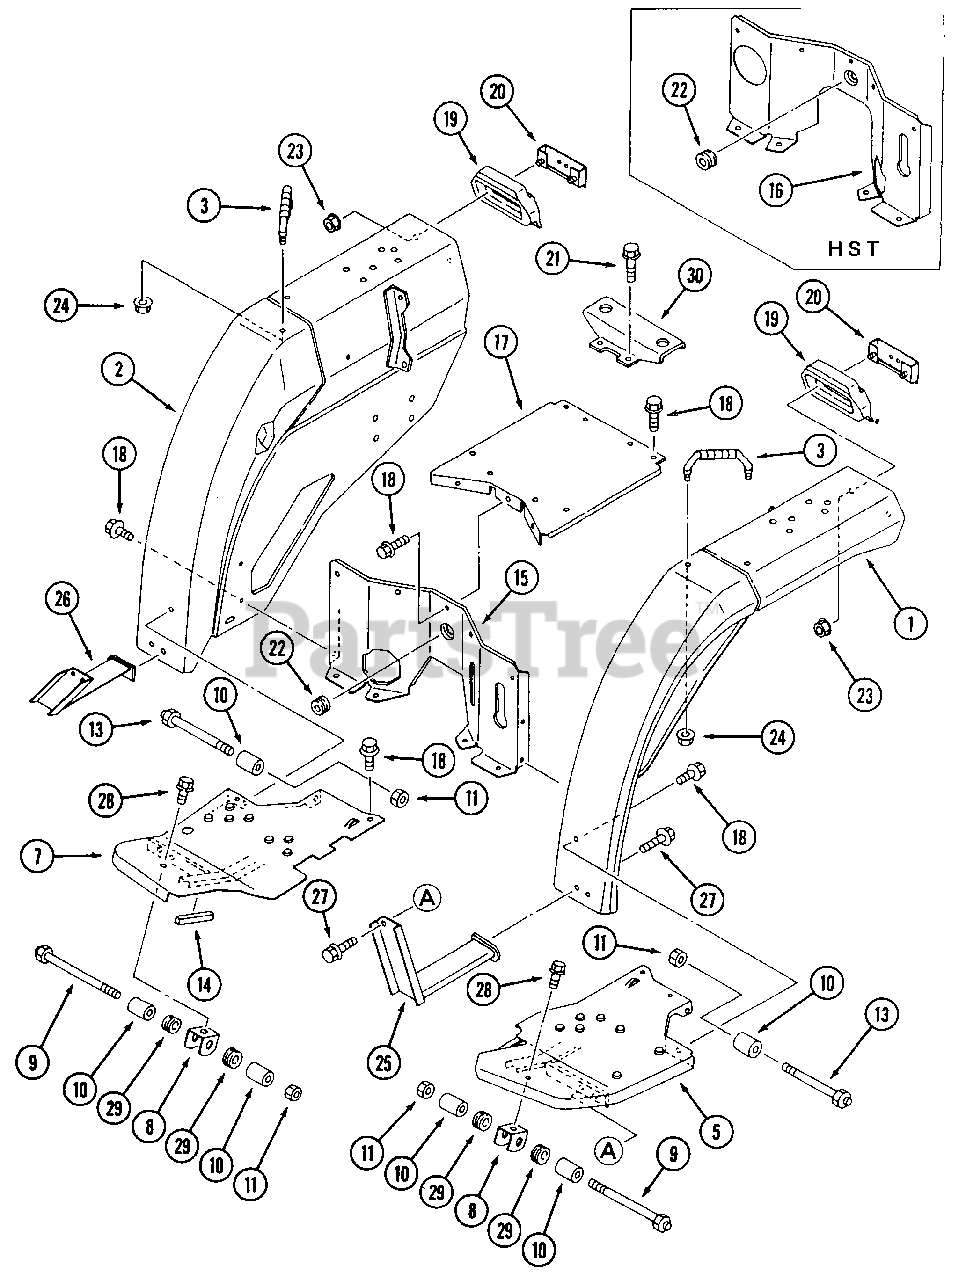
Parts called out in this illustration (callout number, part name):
14	Rubber
16	Cover, Front
25	Step, Sub L.H.
26	Step, Sub R.H.
